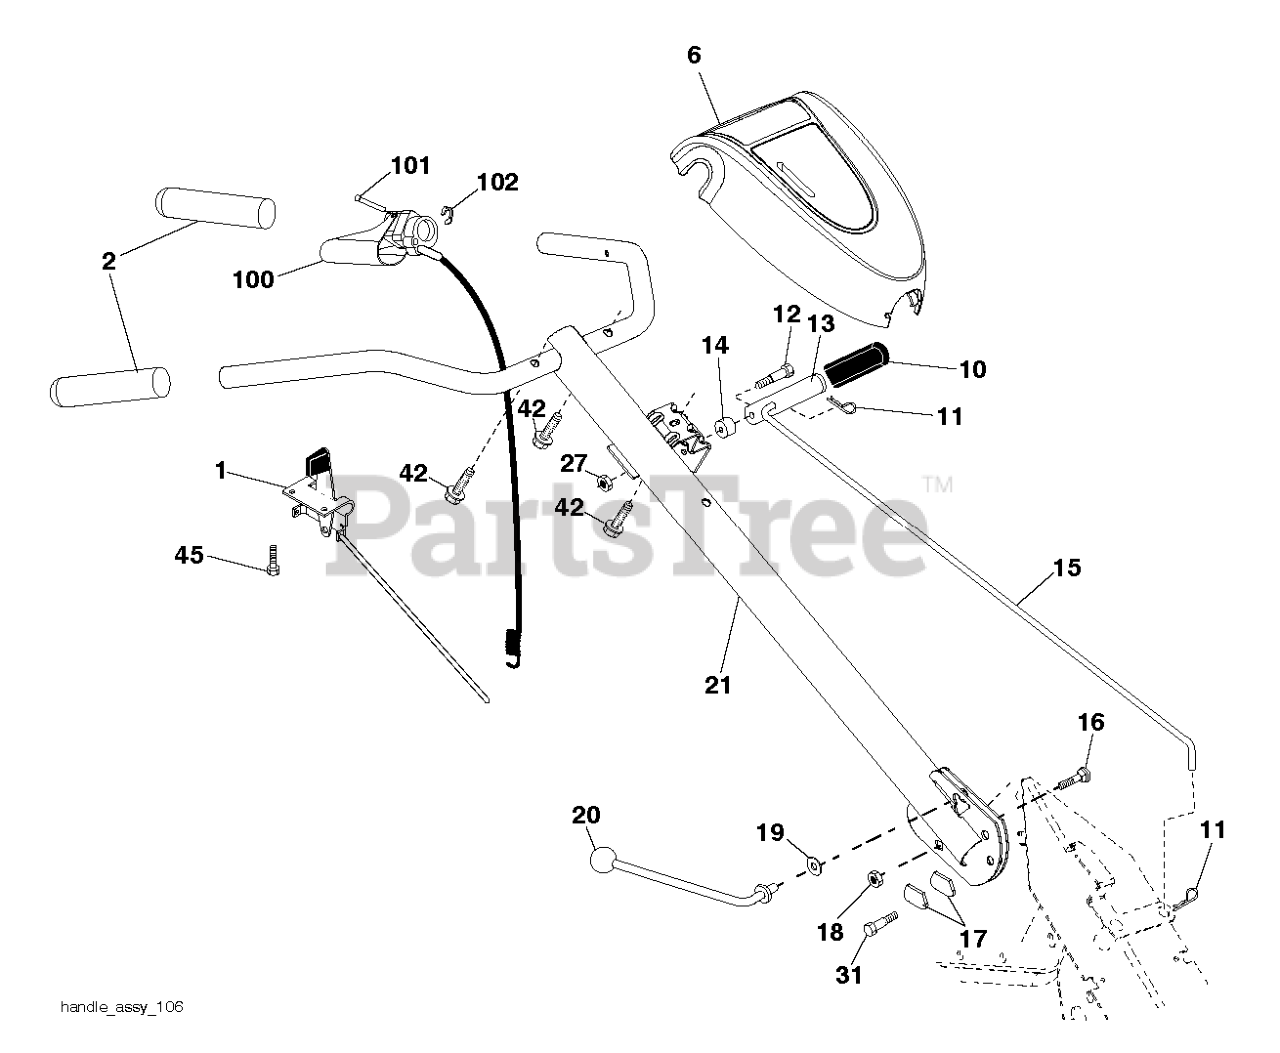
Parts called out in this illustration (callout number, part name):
1	THROTTLE.CONTROL.RT.INTEK.50
2	GRIP.1X5.06
6	CONSOLE.GREY.DRT.W.S.DRT900E
10	GRIP T
11	RETAINER M
12	SHOULDER BOLT ST
13	HANDLE.SHIFT.TILLER
14	GROMMET.RUBBER.CRT.TILLER
15	SHIFT ROD CRT
16	BOLT D
17	LOCK.HANDLE.CRT
19	WASHER CRT
20	LEVER.LOCK.CRT
21	HANDLE.ASM.HUSQ/P.PRO.GREY
27	NUT T
31	BOLT.PIVOT
42	SCREW.#10 X 0.750.BOS
45	SCREW.#10 X 0.500
100	CONTROL.ASSEMBLY.TINE.TILLER
101	PIN, PIVOT
102	RETAINING.RING.#5103-25
